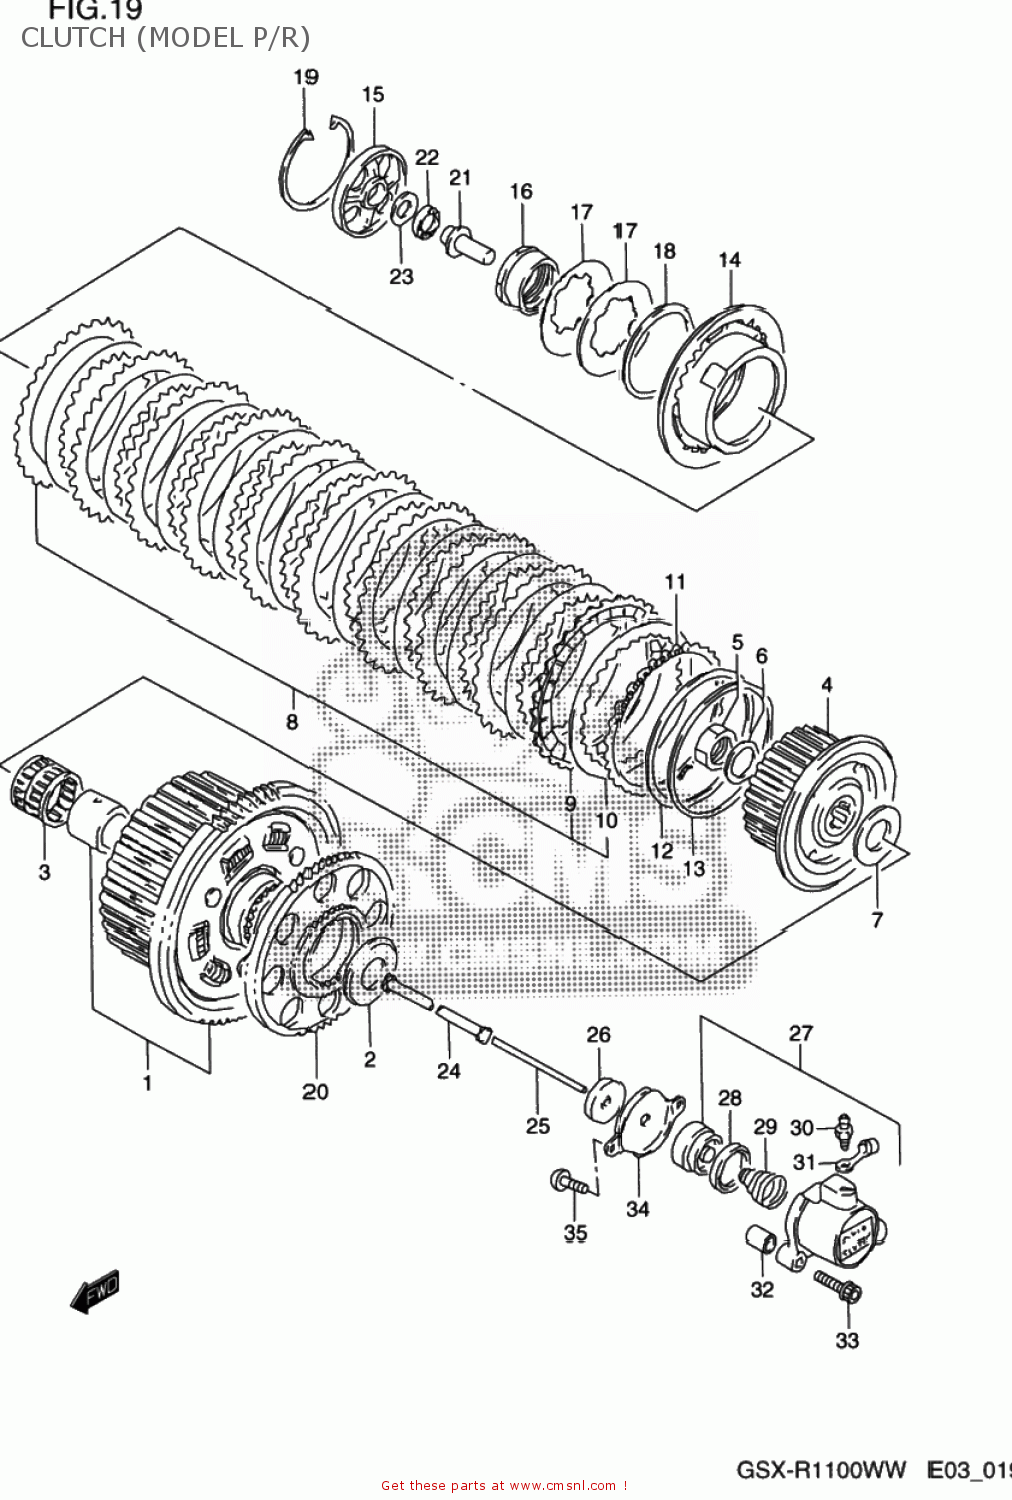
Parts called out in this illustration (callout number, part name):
1	GEAR ASSEMBLY,PRIMARY DRIVE
2	WASHER(25X54X2.5)
3	BEARING(35X40X35.8)
4	HUB,CLUTCH SLEEVE
5	NUT
6	WASHER
7	WASHER(25X50X2.5)
8	PLATE ASSEMBLY,CLUTCH
9	PLATE,CLUTCH DRIVE NO.1 (NAS)
10	PLATE,CLUTCH DRIVEN (NAS)
11	PLATE,CLUTCH DRIVE NO.2
12	WASHER
13	SEAT,CL SLEEVE HUB WAVE WASHER
14	DISC,CLUTCH PRESSURE
15	LIFTER,CLUTCH PRESSURE DISC
16	HOLDER,CLUTCH SPRING
17	WASHER
18	SEAT,CLUTCH SPRING
19	CIRCLIP
20	GEAR,GENERATOR DRIVE
21	PIECE,CLUTCH PUSH
22	BEARING(15X28X2)
23	WASHER
24	ROD,CLUTCH
25	ROD,CLUTCH PUSH,L
26	SEAL,OIL(6X34X5.5)
27	CYLINDER,CLUTCH RELEASE
28	CUP
29	SPRING,CLUTCH CYLINDER
30	BLEEDER
31	CAP,BLEEDER
32	PIN
33	BOLT
34	COVER,CLUTCH RELEASE CYLINDER
35	SCREW
